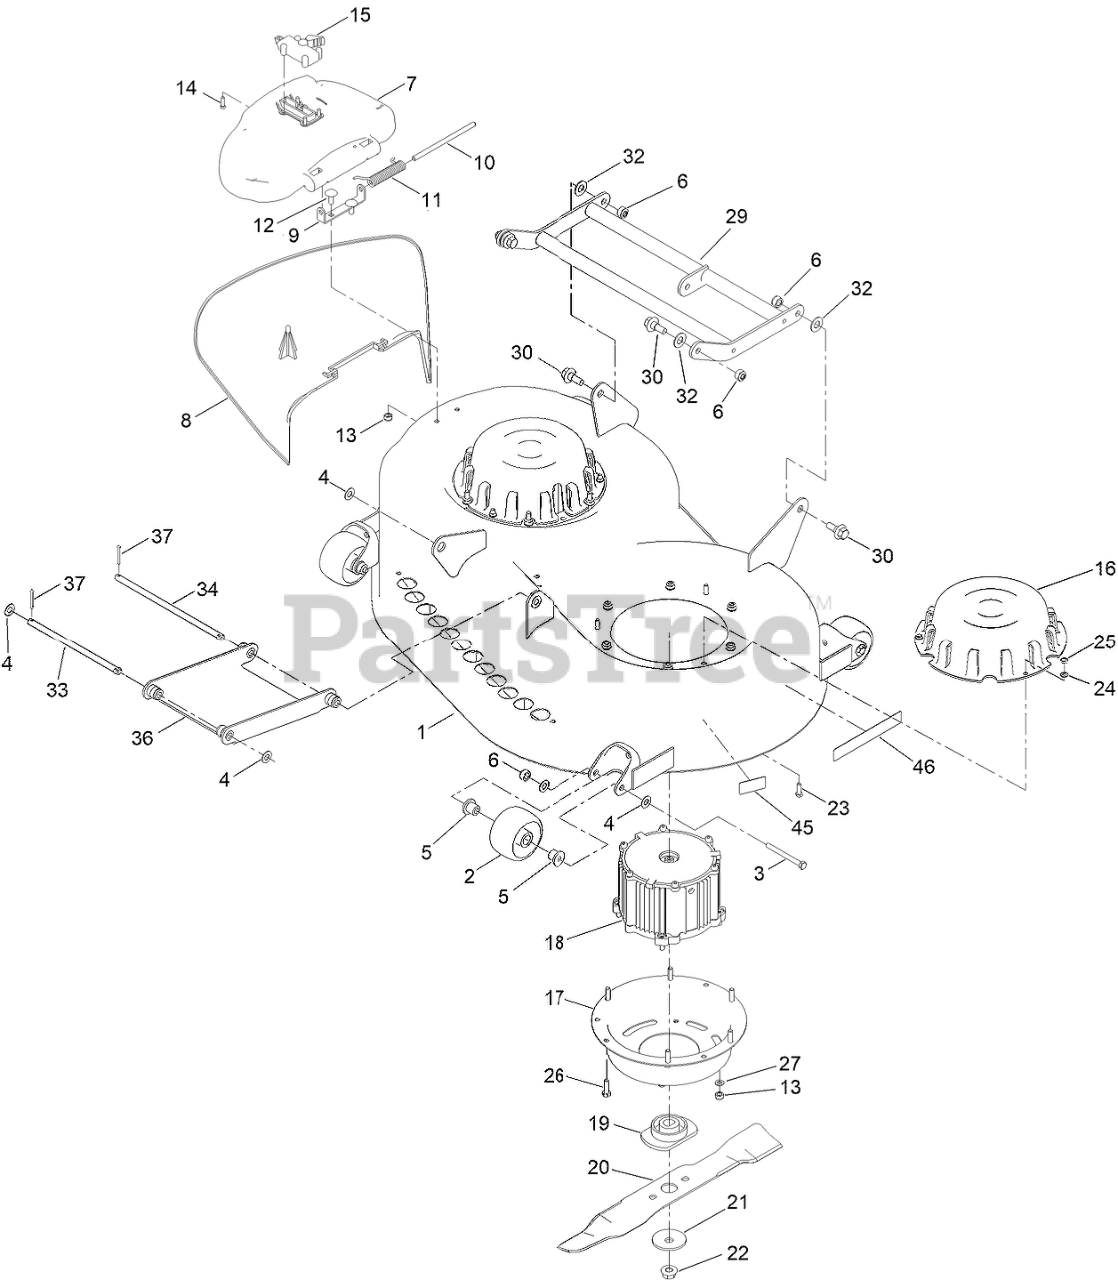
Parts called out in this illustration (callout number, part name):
1	WELDED DECK ASM
2	WHEEL, DECK
3	BOLT-HH
4	WASHER-PLAIN
5	INSERT, DECK WHEEL
6	NUT-HEX, NI
7	COVER, DECK CHUTE
8	CHUTE, DECK
9	BRACKET, DISCHARGE FLAP
10	ROD, DISCHARGE FLAP
11	SPRING, DISCHARGE FLAP
12	BOLT-CARRIAGE
13	NUT-NYLOC
15	DECK CHUTE CLIP, ASM
16	TOP COVER, DECK MOTOR
17	BOTTOM COVER, DECK MOTOR
18	MOTOR, DECK
19	HUB, BLADE MOTOR
20	BLADE, DECK
21	WASHER, BLADE
22	NUT, BLADE
23	SCREW-HH
24	WASHER
25	NUT-NYLOC
26	SCREW-HHF
27	WASHER-PLAIN
29	REAR HOC LIFTING ASM
30	BOLT, FLANGE
32	WASHER-PLAIN
33	ROD, FRONT DECK MOUTNING (SHORT)
34	ROD, FRONT DECK MOUTNING
36	MOUNTING BRACKET ASM, DECK
45	DECAL - NO SPRAY
46	DECAL - DECK WARNING
